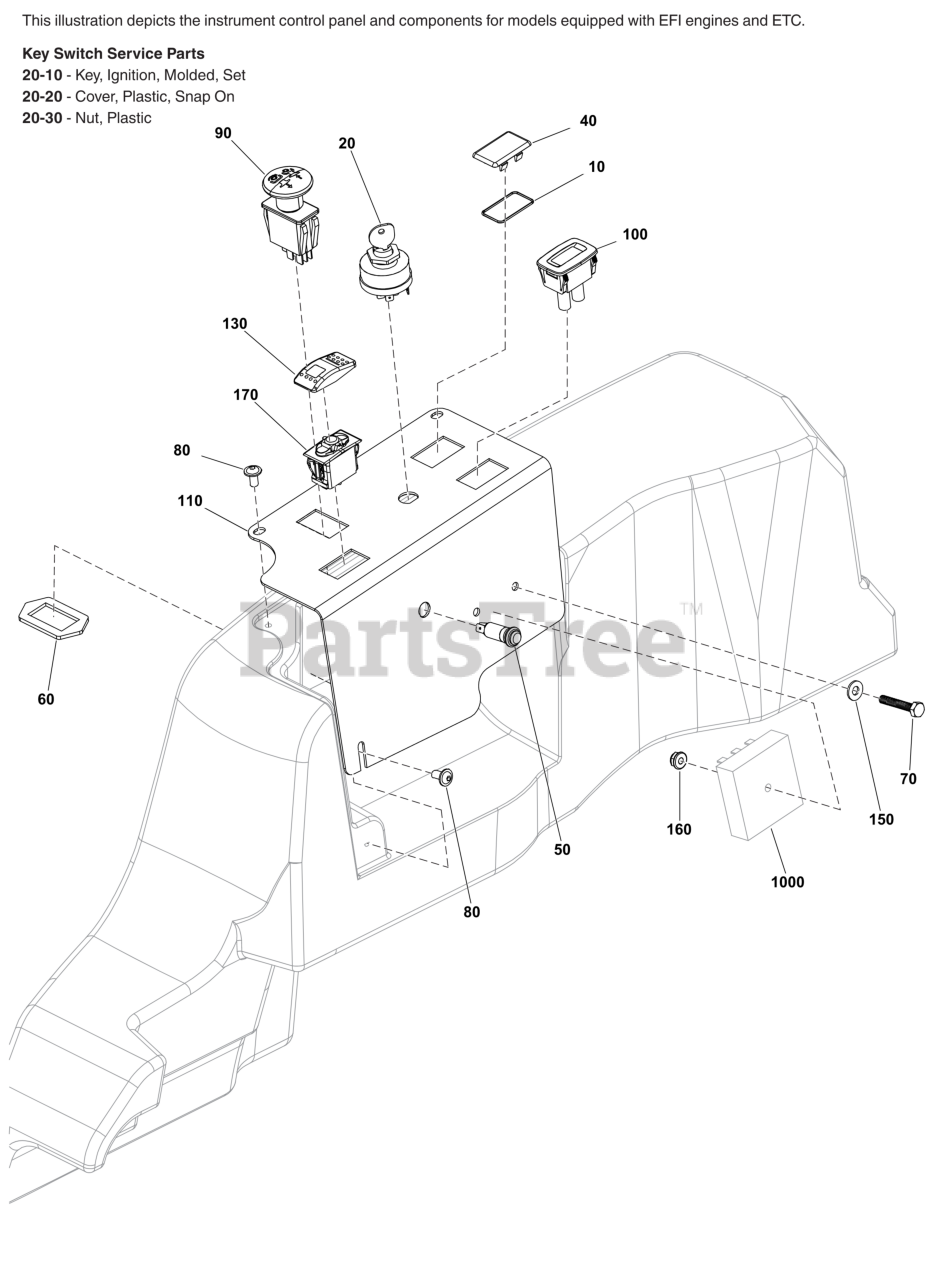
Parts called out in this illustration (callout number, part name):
10	O-RING, 7/8" ID X 1/1
20	SWITCH, IGNITION
20-10	KEY, IGNITION MOLDED SET
20-20	COVER, PLASTIC, SNAP ON
20-30	PLASTIC NUT
40	PLUG, BLACK PLASTIC
50	LIGHT, Indicator
60	RING, SWITCH RETAINER
80	SCREW, FLANGE
90	SWITCH-PTO PUSH
110	PLATE, CONTROL PANEL, S125XT,KAV EFI - BLK
130	SWITCH, ROCKER
150	WASHER
170	BODY, ROCKER SWITCH
1000	Refer to: Instrument Control Panel Group
